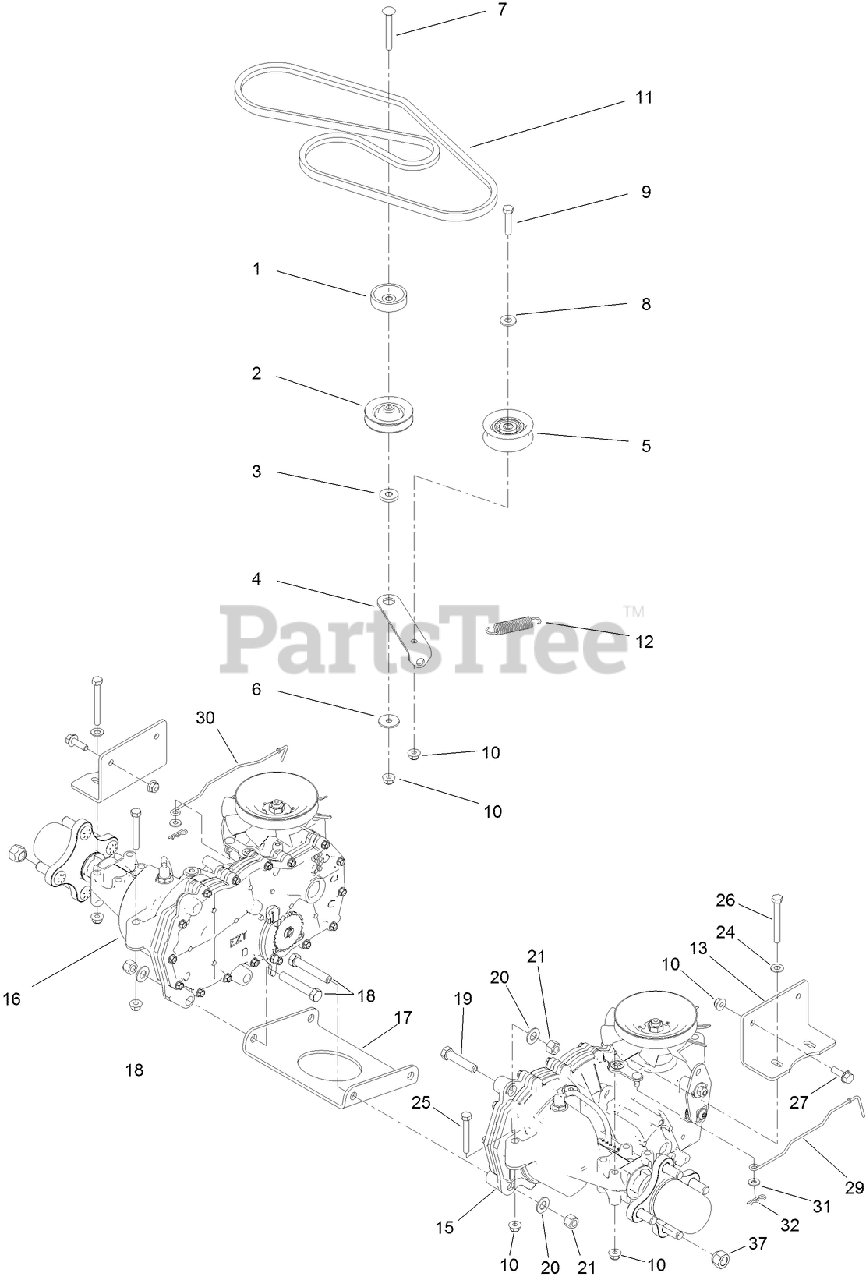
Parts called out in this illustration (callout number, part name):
1	SPACER
2	PULLEY-IDLER
3	SPACER-ARM, IDLER
4	ARM-IDLER
5	PULLEY-IDLER
6	WASHER-PIVOT
7	SCREW-CARR
8	WASHER-FLAT
9	SCREW-HH
10	NUT-HF, NI
11	V-BELT
12	SPRING-RETURN, PEDAL
13	MOUNT-HYDRO
15	LH HYDRO TRANSAXLE ASM
16	RH HYDRO TRANSAXLE ASM
17	PLATE-CROSS, HYDRO
18	SCREW-HH
19	SCREW-HH
20	WASHER-FLAT
21	NUT-LOCK, NI
24	WASHER-PLAIN
25	SCREW-HH
26	SCREW-HH
27	SCREW-HHF
29	ROD-BYPASS, LH
30	ROD-BYPASS, RH
31	WASHER
37	NUT-LUG
